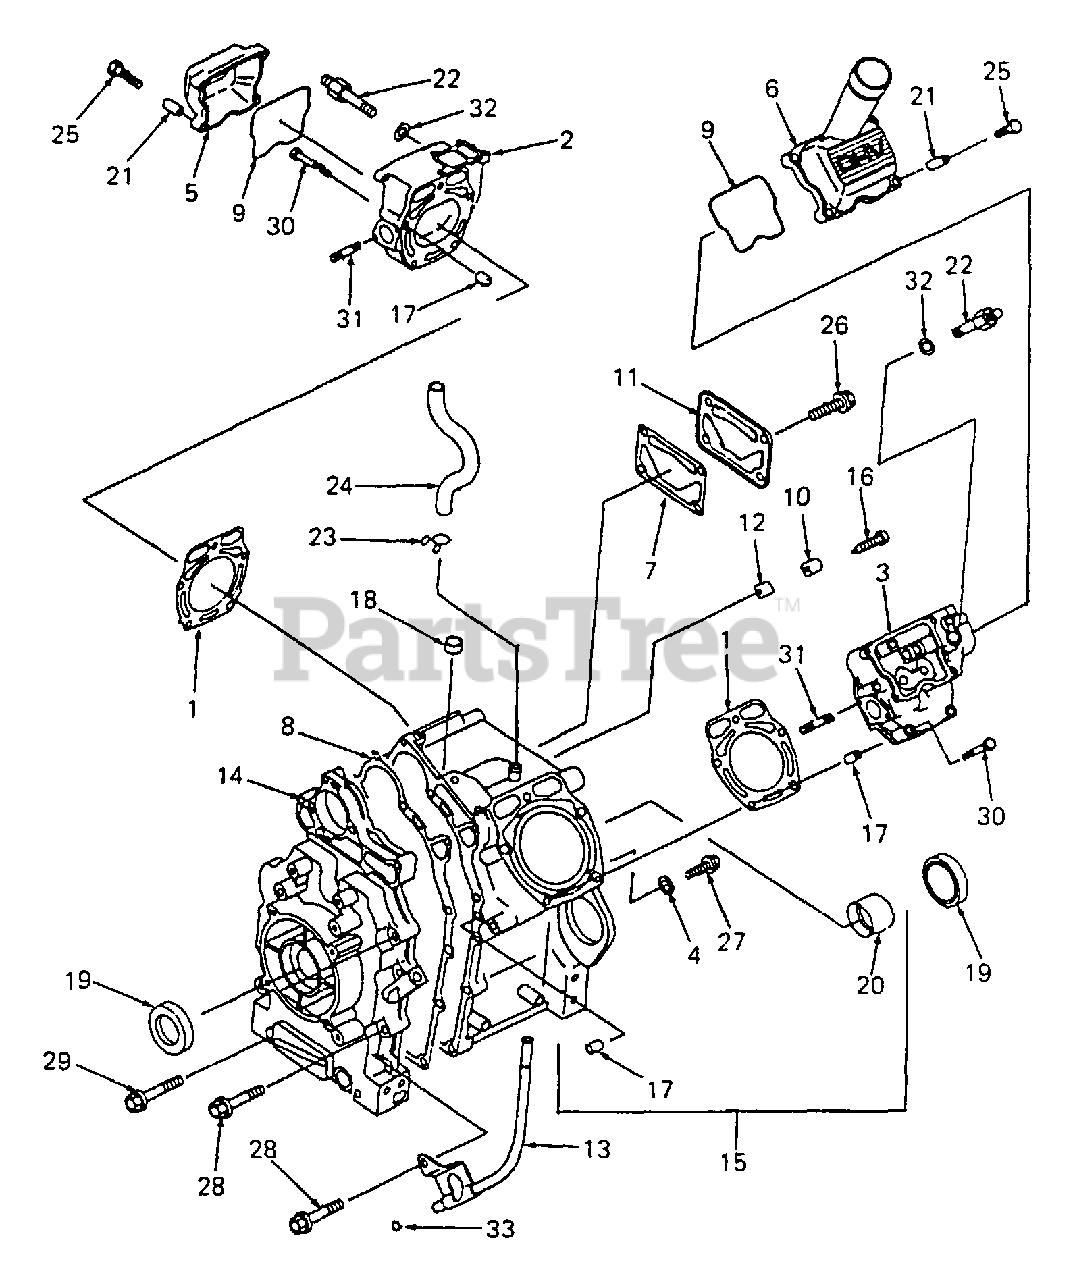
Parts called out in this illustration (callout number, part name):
2	Head Complete, Cylinder
3	Head Complete, Cylinder
6	Cover, Valve w/Oil Fill
7	Gasket, Cover
8	Gasket, Crankcase Cover
9	Gasket, Valve Cover
13	Pipe, Oil Gauge
14	Cover, Crankcase
15	Crankcase Complete
17	Pin, Dowel, 10 x 8.2 x 14
19	Seal, Oil
20	Bearing, Plane
25	Bolt, Flanged, 6 x 25
26	Bolt, Flanged, 8 x 16
27	Bolt, Flanged, 8 x 12
28	Bolt, Flanged, 8 x 45
29	Bolt, Flanged, 8 x 60
30	Bolt, Flanged, 8 x 65
31	Bolt, Stud, 6 x 20
32	Washer, Plain, 8 MM
33	O-Ring, 10 MM
